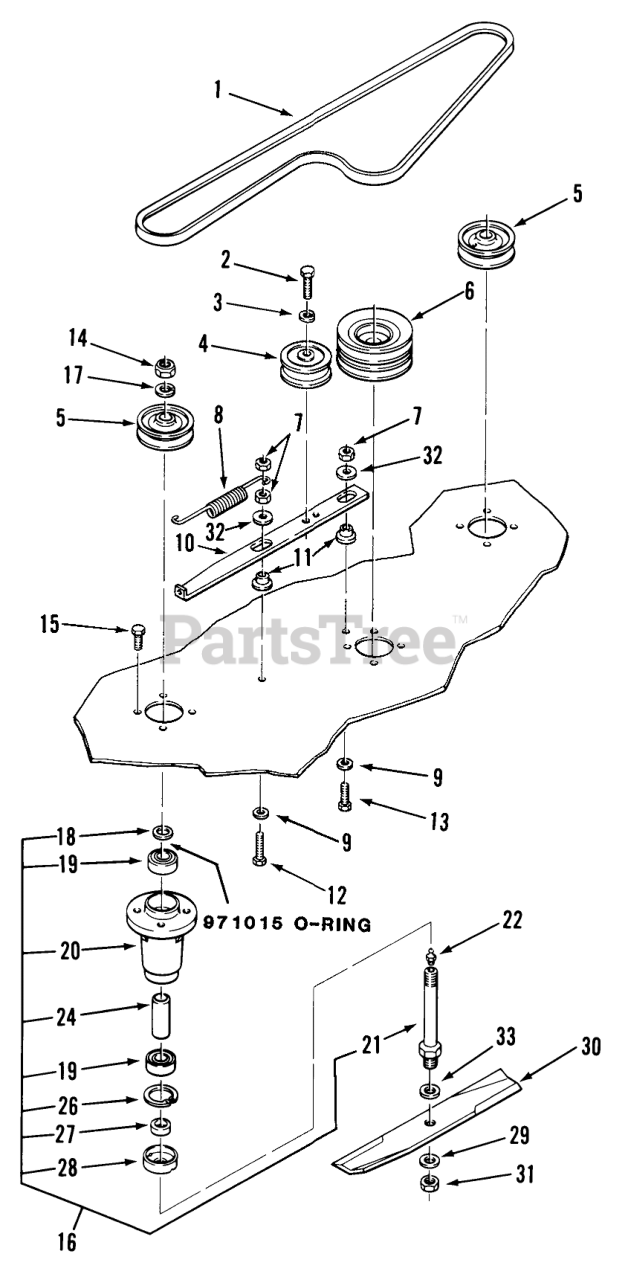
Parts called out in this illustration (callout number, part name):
1	V-BELT
2	BOLT HEX SPECIAL
3	LOCKWASHER
4	Idler Pulley
5	PULLEY
6	PULLEY CENTER
7	NUT
8	SPRING-EXTENSION
9	WASHER
10	BAR-IDLER SUPPORT
11	SPACER-BUSHING
12	Bolt
13	Bolt
14	Nut
15	Bolt
16	ASSY 36" SPINDLE
17	Lockwasher
18	Washer
19	BEARING-BALL
20	HOUSING-SPINDLE
21	Spindle Shaft
22	Zerk
24	Spacer
26	Ring-Snap
27	SPACER-BLADE
28	CUP-SPINDLE
29	SpeciaI Washer
30	S/A BLADE KIT
31	Nut
32	WASHER
33	Washer
